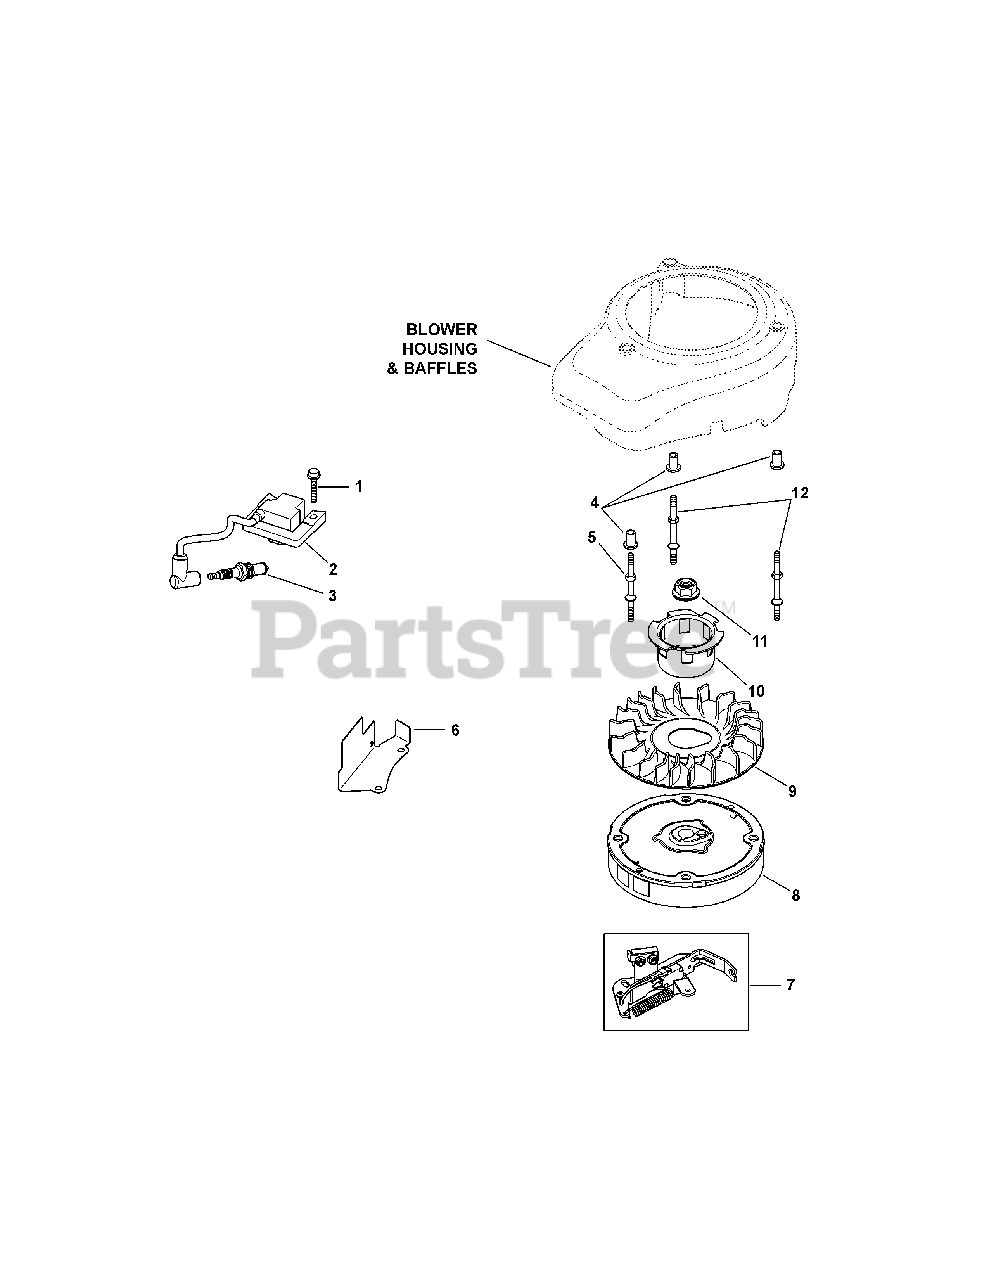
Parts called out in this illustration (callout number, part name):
1	Screw, Hex Flange (M6)
2	Module, Ign (Alum Std Ign)
3	Plug, Spark (Std)
5	Stud
7	Brake Assembly, Carb Side
8	Flywheel (Aluminum)
9	Fan, Flywheel
11	Nut, Flywheel (W/Serrations)
12	Stud
